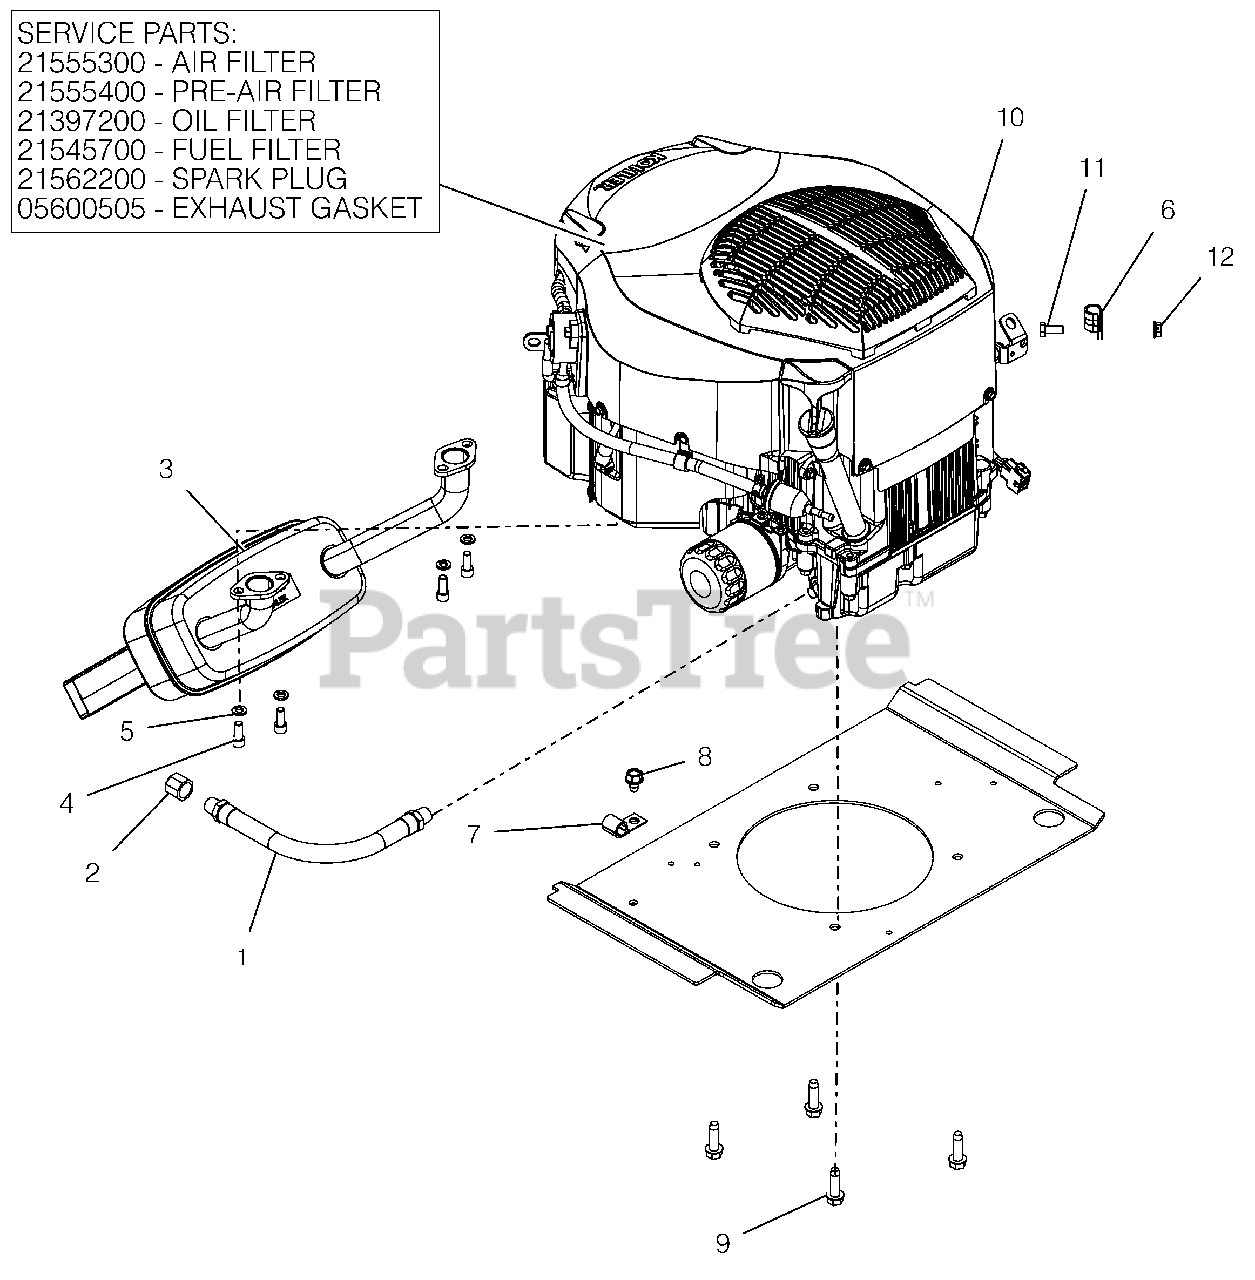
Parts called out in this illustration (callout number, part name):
1	HOSE,HYD .38-11-0K M6NO-M6N0
2	PIPE CAP 3/8 NPT FEMALE
3	MUFFLER, KOHLER
4	SCR-CAP .31-18X.75 S/HD
5	@WSHR-LK .31X.078 REG YWZC
6	CLAMP, CUSHIONED STEEL
8	@SCR-TAP .38-16X.50 HWH TR YWZ
9	@SCR-TAP .38-16X1.25 HWH TR YZ
10	ENGINE-KOHLER TWIN 26 PRO W/SC
10	AIR FILTER, KOHLER
10	PRE CLEANER, KOHLER
10	FILTER, OIL - KOH CV20
10	FILTER-FUEL KOHLER COURAGE PRO
10	PLUG, SPARK (RFI)
10	GASKET, MUFFLER KOHLER TWIN
11	@BLT-HEX .31-18X.75 GR5 YWZC
12	@NUT-LK-CTR-FLG .31-18 YZ GR F
